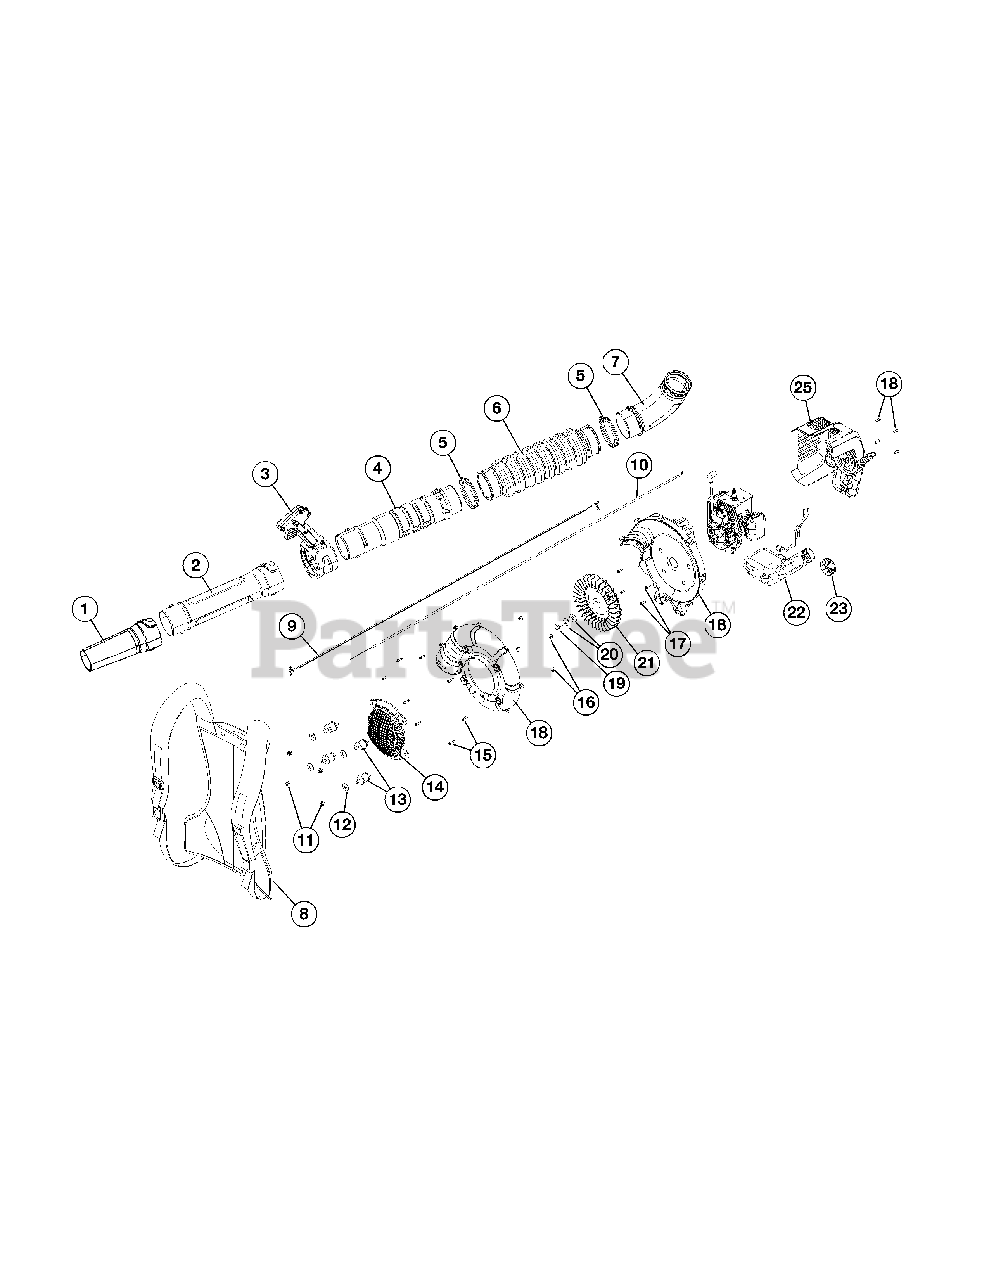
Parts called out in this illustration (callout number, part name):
2	Lower Blower Tube
3	Throttle Grip Assembly
4	Upper Blower Tube
8	Harness
10	Throttle Cable
11	Nut
13	Insulator Mount
14	Intake Cover
16	Nut
17	Screw
18	Impeller Housing Assembly
20	Impeller Hardware
21	Impeller
22	Fuel Tank Assembly
25	Starter Housing Assembly
